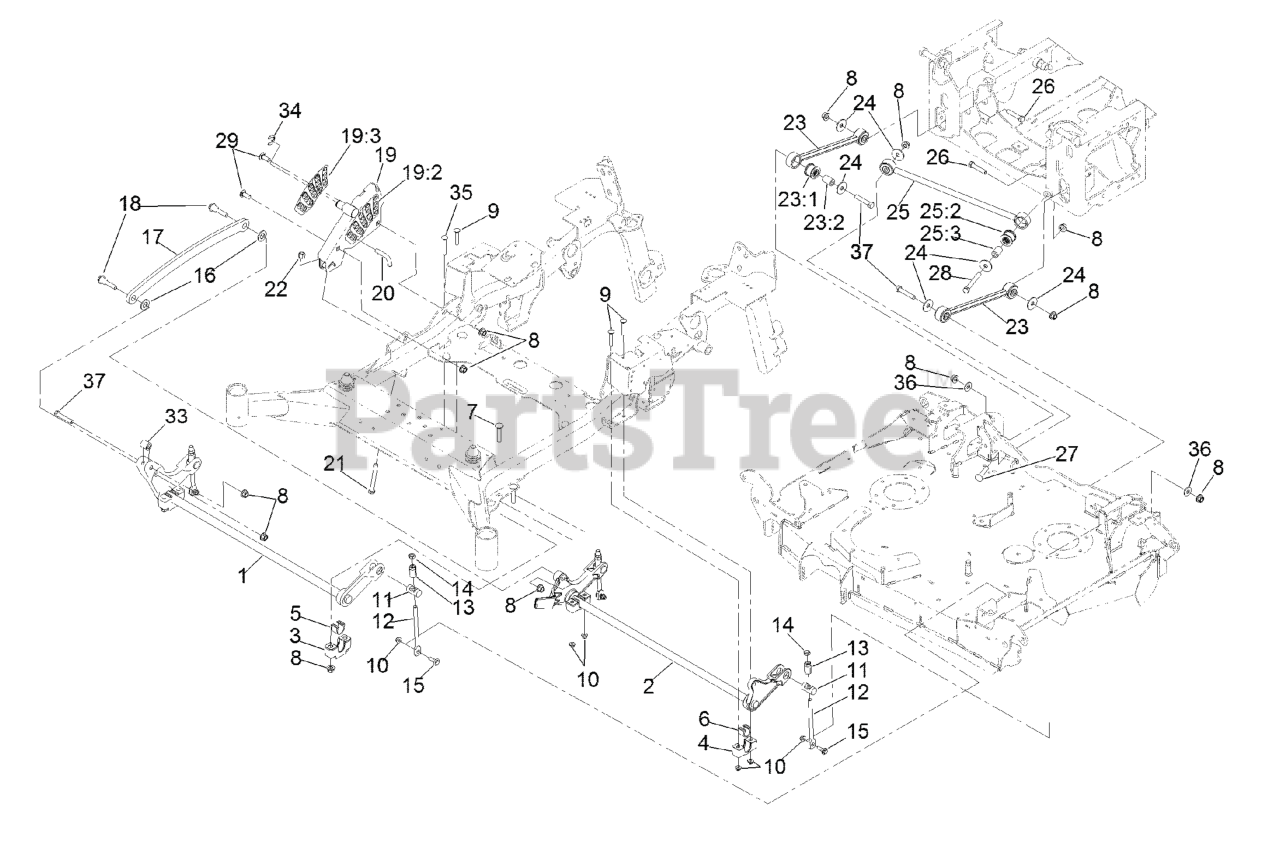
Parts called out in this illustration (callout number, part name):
1	DECKLIFT-FRONT
2	LIFT-DECK, REAR
3	SUPPORT-CROSS SHAFT, BEARING
4	SUPPORT-CROSS SHAFT, BEARING REAR
5	BEARING-CROSS SHAFT, FRON
6	BEARING-CROSS SHAFT, REAR
7	Bolt-Carriage 1/2-13 X 2 1/2 Spl Neck
8	Nut-Lock 1/2-13
9	Bolt-Carriage 3/8-16 X 2 1/4
10	NUT-HF, NI
11	TRUNNION
12	LINK-ADJUSTER, DECK LIFT
13	ADJUSTER-LIFT, DECK
14	NUT-JAM
15	SCREW-SHOULDER, HHF
16	WASHER-FLAT
17	LINK-LIFT, DECK
18	SCREW-HHF, SHOULDER
19	HOC ASM
19:2	DECAL-HEIGHT OF CUT
19:3	DECAL-HEIGHT OF CUT, OUTER
20	PIN-HOC
21	BOLT-TAP
22	NUT-LOCK, NI
23	DECK STRUT ASM
23:1	BUSHING-SUSPENSION, RUBBER
24	WASHER-THRUST
25	PANHARD ROD ASM
25:2	BUSHING-SUSPENSION, RUBBER
26	SCREW-HH
27	SCREW-CARR
28	SCREW-HH
29	SCREW-CARR, SHORT NECK
33	SPACER-PIVOT
34	RING-RETAINING
35	SCREW-CARR
36	WASHER-SPRING
37	SCREW-HH
